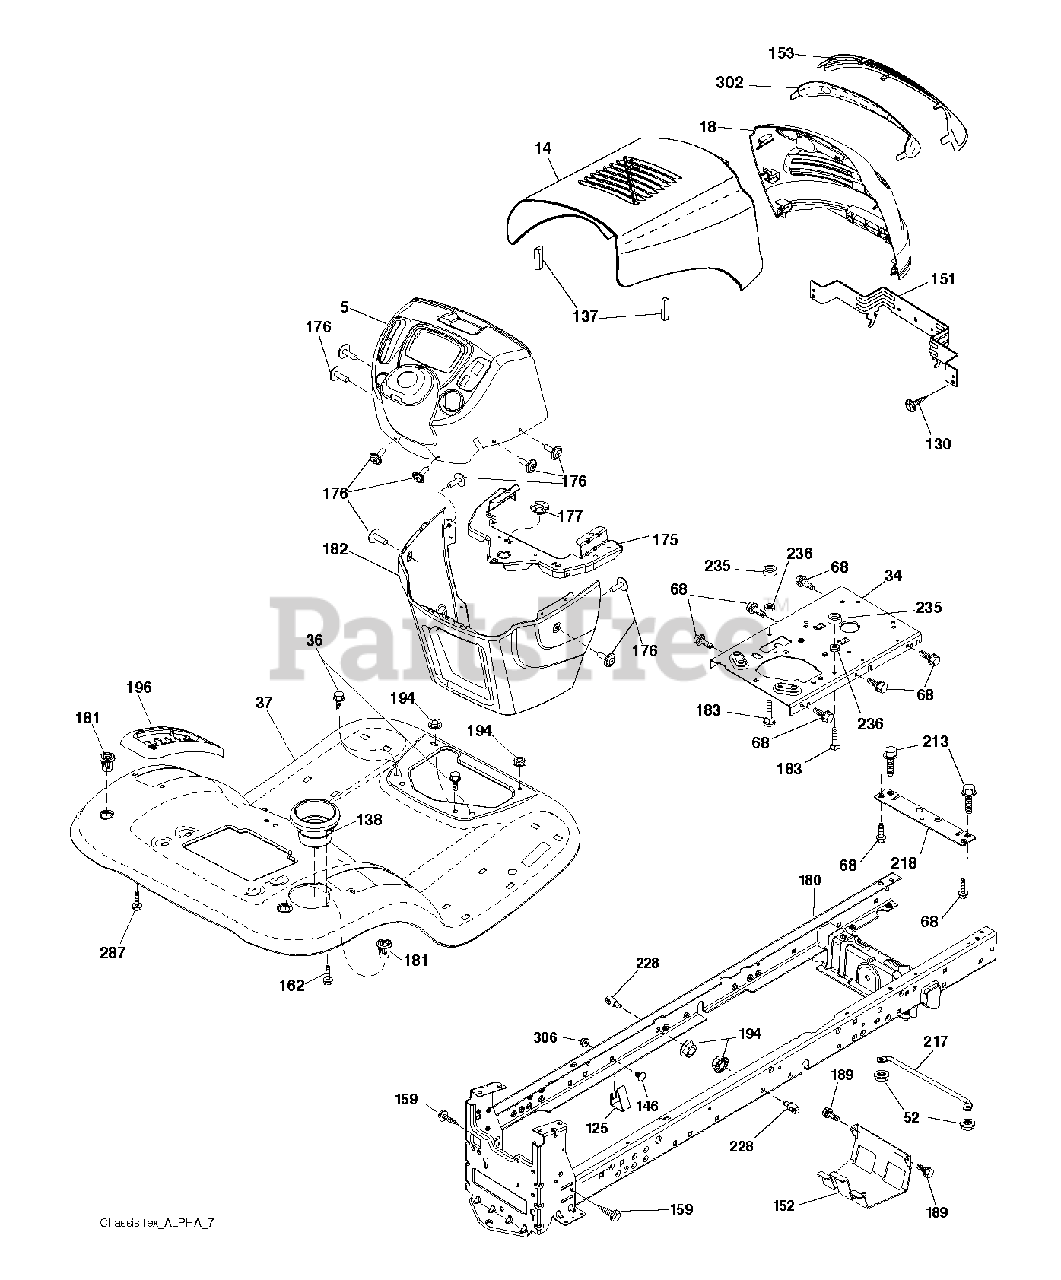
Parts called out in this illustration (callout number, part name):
5	DASH.P/L.TEX.CBL.CL.N/CHK.BLAC
14	HOOD.BLACK.ALPHA
18	GRILLE.ASM.ALPHA
34	PLATE.ENGINE.WELDED.CHASSIS
36	SCREW 5/16"
37	FENDER.TLT.FS.W/CPH.428
52	LOCKNUT
68	SCREW LT
125	CLIP.FUEL.LINE
130	SCREW.#10 X 0.750.BOS (2 2)
137	BUMPER.HOOD.LARGE.1.75"
138	CUPHOLDER.TL.TEX.BLACK
146	BOLT.RDHD.SHT.SQNK.3/8-16X5/8
151	BRACKET.PIVOT.ALPHA.LT
152	SHIELD.BROWNING.W/TEX
153	LENS.ALPHA.BAR.LT
159	SCREW, 3/8-16X3/4
162	SCREW.HI-LO.CONSOLE
175	CROSSMEMBER.LT
176	SCREW.#10-24X5/8.RN.QU
177	BUSHING STEERING
180	CHASSIS
181	FEND/FTRST.PCH.CPH.NFW
182	DASH.LOWER.LT.CCS
183	BOLT.5/16-18X1-1/4 FULL THD
189	SCREW
194	NUT LOCK HEX FLANGE 5/16-18
196	CONSOLE.ASM.DECKLFT.BL/RBT.TLT
213	BOLT
217	ROD.PIVOT.HOOD
218	X-PIECE.HOOD.STOP.NON/
228	STUD.FASTNER.W/ANTI-ROTATE
235	SPACER FENDER
236	NUT.CENTERLOCK.5/16-
287	SCREW 1/4X20
302	INSERT.ALPHA.REFLECTIVE.LT.
306	NUT LOCK FLG 3/8-16 UNC
